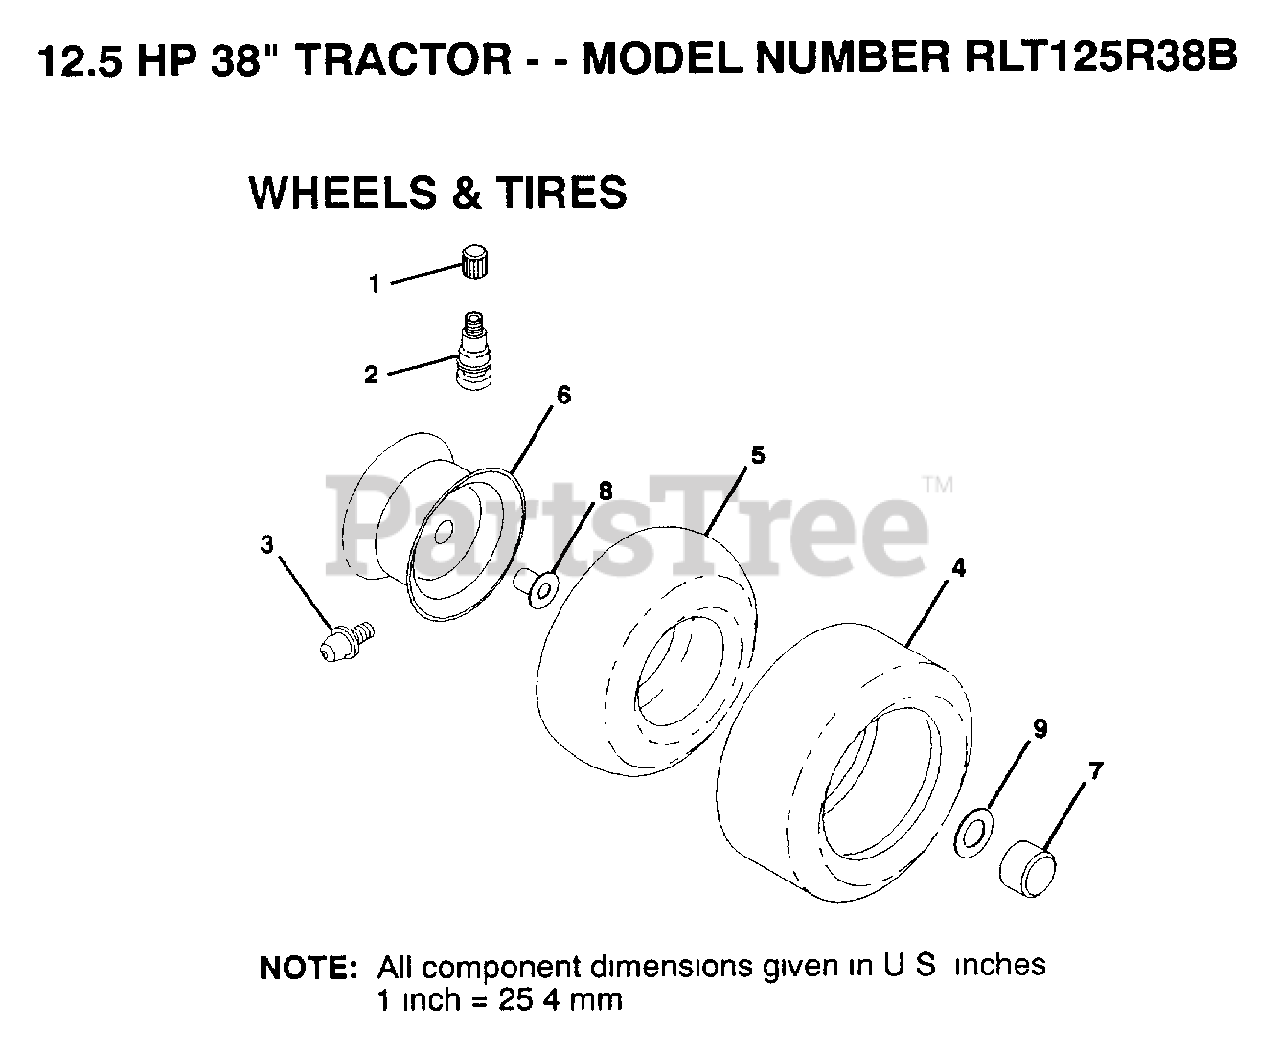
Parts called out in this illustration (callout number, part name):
1	VALVE CAP
2	VALVE STEM LT
3	FITTING LT
5	TUBE.5.3/4.5/6
5	TUBE.16X6.5/7.5-8
7	HUB CAP
8	"FLANGE, BEARING"
9	WASHER
